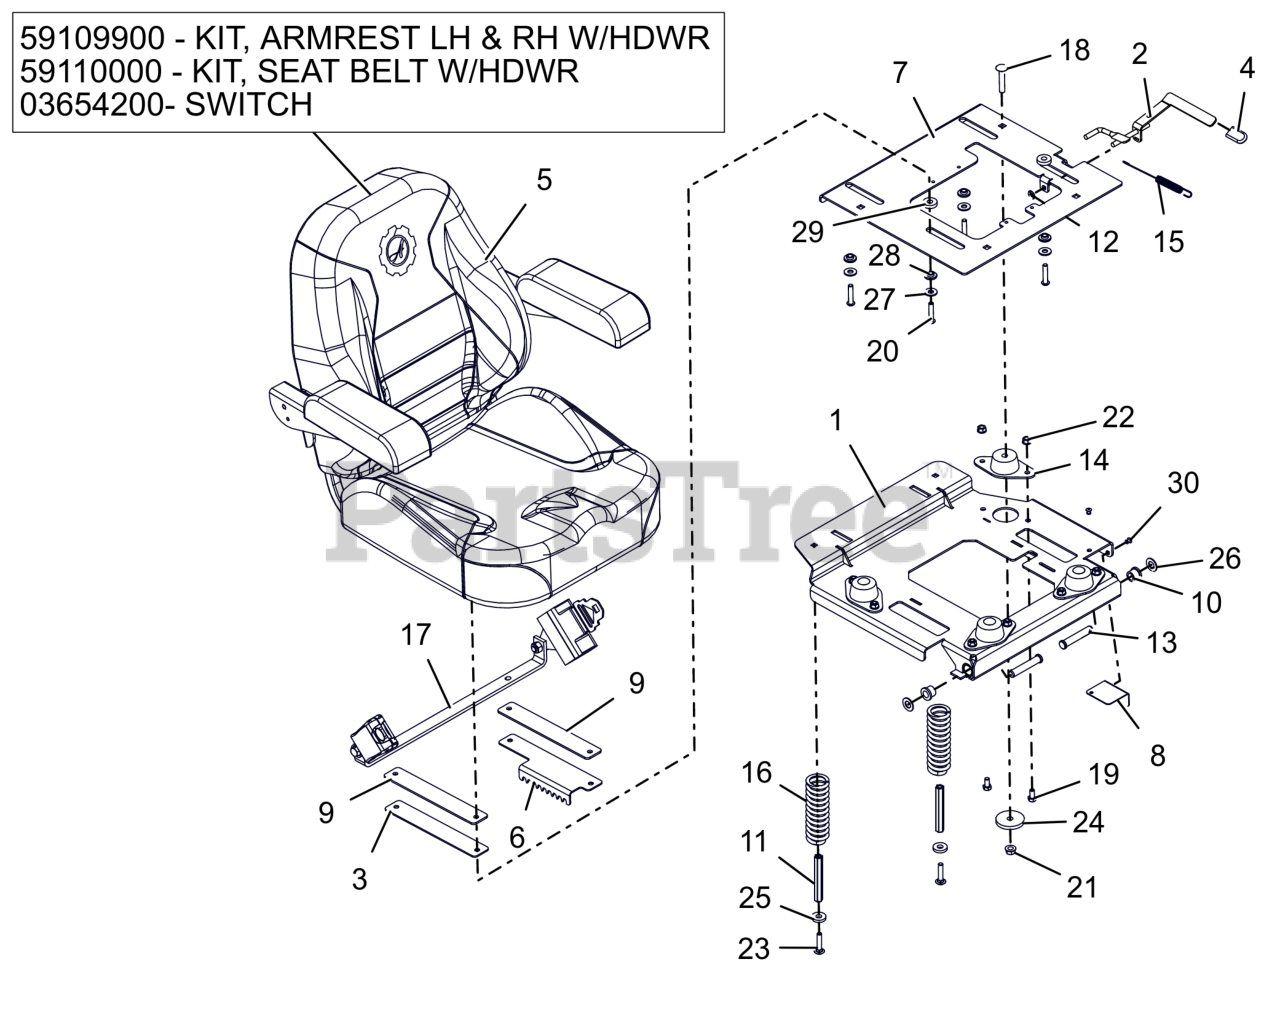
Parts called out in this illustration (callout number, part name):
1	WLDMT, ISO MTG PLATE (BLACK)
2	WLDMT, SEAT SLIDE LEVER
3	PLATE, ADJUSTABLE SEAT SLIDE
4	GRIP, SEAT LEVER, GREY
5	SEAT, APEX
5	KIT, LH&RH ARM REST-05007300
5	SWITCH- SEAT
5	KIT-SEAT BELT REPLACE-05007300
6	PLATE, HD SEAT ADJUSTMENT
7	PLATE, SEAT MOUNTING (ISO KIT) (ORANGE)
8	GUARD, SEAT FAN (SH)(BLACK)
9	SPACER, SEAT
10	BSHG, FLG .516X.750X.625X.937
11	NUT, COUPLING 5/16X18 X 3.75
12	NUT-PUSH .312
13	PIN-CLIC .50X2.70X2.31 -ZCC
14	MOUNT, FAIL-SAFE COMPRESSION
15	SG-TENS .06X.482X5.35
16	SPRING, COMPRESSION SEAT 224LB
17	KIT-SEAT BELT REPLACE-05007300
18	BLT,RHSSN.375-16X2.00 G5 ZCC
19	BLT, HEX .31-18X.625 G5 ZCC
20	BLT,SHCS-BTN .31-18X1.50 ZCC
21	NUT-LK-CTR-FLG .375-16 GF ZCC
22	NUT,LK-CTR-FLG .31-18 GF ZCC
23	BLT,RHSN .31-18X1.50 G5 ZCC
24	WSHR-FL-STL 0.406X2X0.25 ZCC
25	WSHR, FLT .406X1.00X.188 ZCC
26	WSHR, FLT .531X1.00X.063 ZCC
27	WSHR,FLT .375X.875X.083 ZCC
28	BSHG-FLG .325X.499X.3X.875
29	WSHR, FLT .390X1.00X.250 ZCC
30	RIVET, .1875 AL/AL .126-.250
